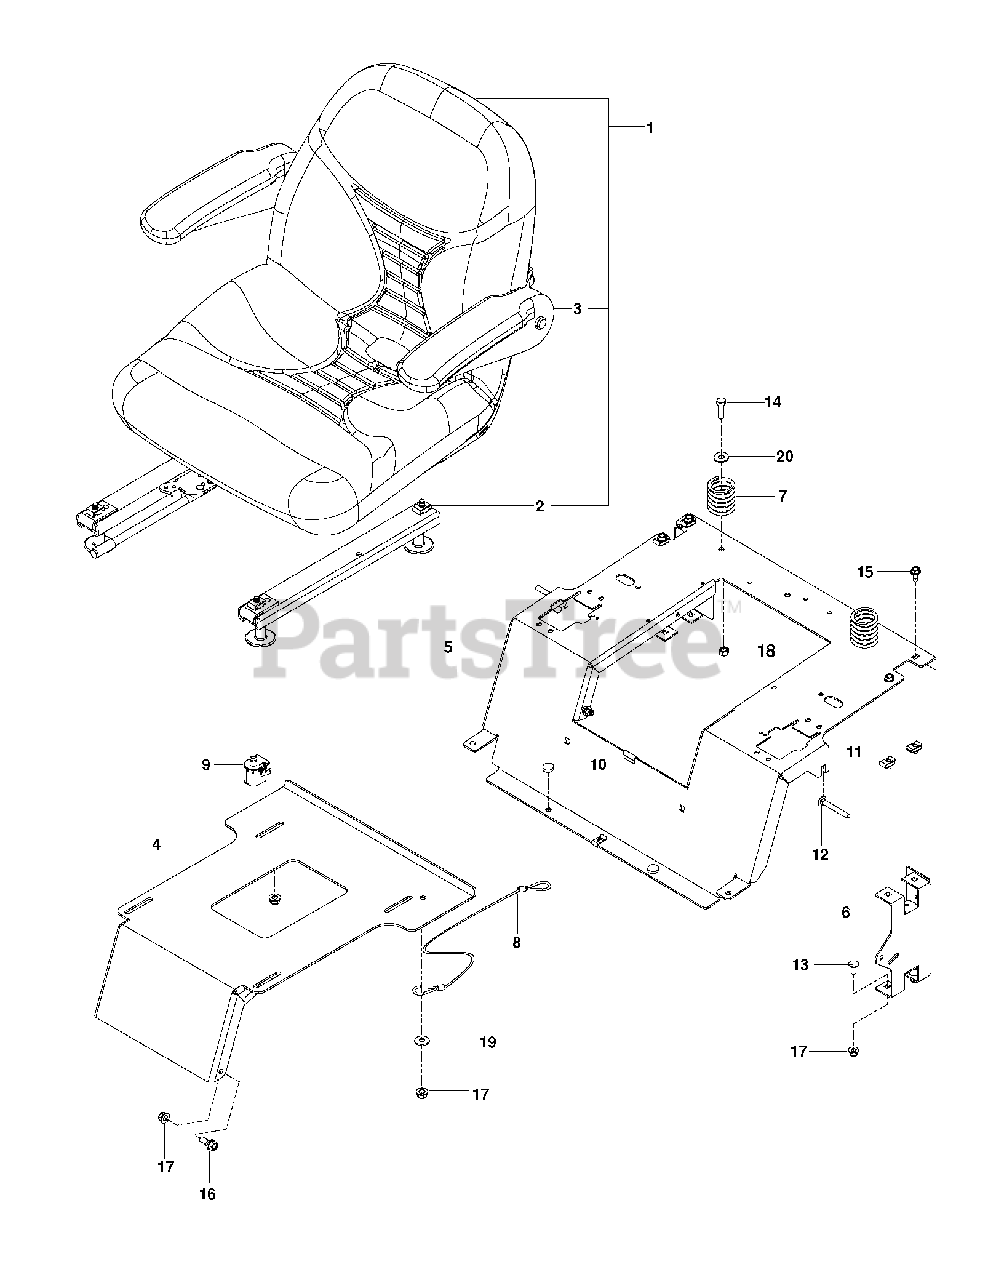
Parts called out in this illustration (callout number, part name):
1	SEAT
2	TRACK ADJUSTMENT KIT
3	ARMREST KIT, LT SQUARE END
4	PAN, SEAT ORG
5	SUPPORT SEAT FLAT ORANGE
6	SUPPORT REAR SEAT BLACK
7	SPRING, SEAT
8	SEAT LANYARD
9	SEAT SWITCH
10	GROMMET, BUMPER
11	U-CLIP 5/16-18 NUT RETAINER
12	RHSNB 5/16-18 X 2-1/2 GR5 ZD
13	BOLT 5/16C X 3/4" CARRIAGE
14	HCS 3/8C X 1 1/4 GR5
15	BOLT 5/16-18 X 3/4
16	SB 5/16-18 HEX HD GD5, BLK ZN
17	5/16-18 NYLOC FLANGE NUT
18	NUT 3/8-16 NYLOC
19	WASHER 5/16 FLAT
20	RP WASHER 3/8 FLAT
